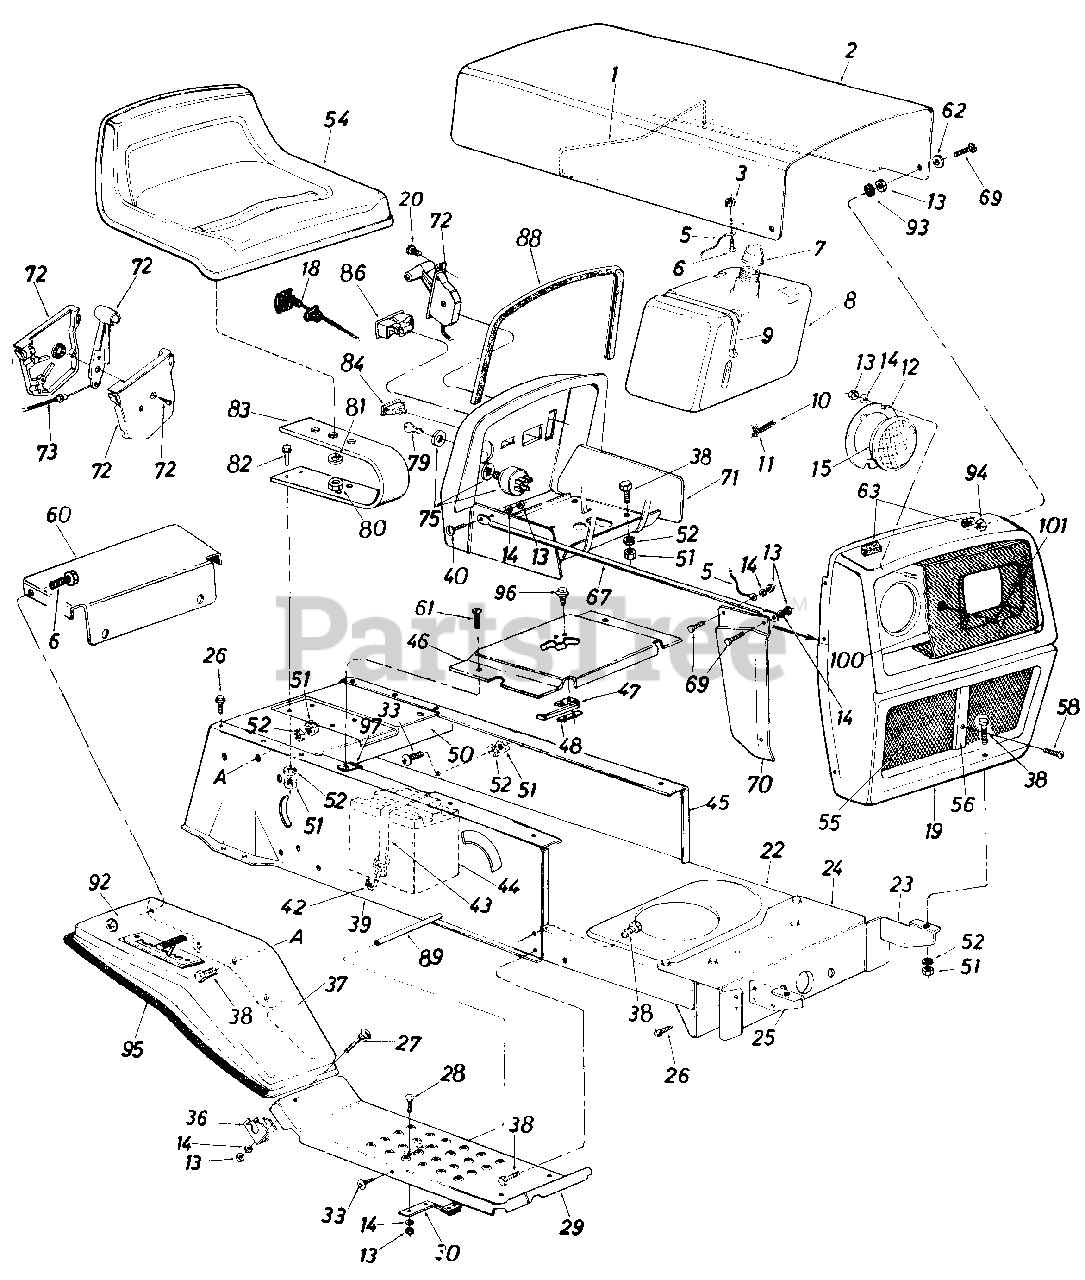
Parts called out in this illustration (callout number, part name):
1	Hood Spring
2	Hood
3	Hex Sems Nut #10-24 Thd.
5	Hood Stop 7" Lg.
6	Truss Hd. Scr. #10-24 x 1/2"
7	Fuel Cap Gauge
8	Fuel Tank
9	Tie Strap
10	Fuel Line
11	Hose Clamp
12	Headlight Retainer
13	Hex Nut 1/4-20 Thd.*
14	L-Wash 1/4" I.D.
15	Headlight
18	Choke Control 29" Lg.
19	Grille Ass'y.
20	Truss Mach. AB-Tap Scr. #10 x .50" Lg.
22	Lower Frame
23	Grille Mount Brkt.-L.H.
24	Front Pivot Brkt.
25	Grille Mount Brkt.-R.H.
26	Hex Wash. Hd. AB-Tap Scr. 5/16 x .75" Lg.
27	Carriage Bolt 1/4-20 x 2.0"*
28	Carriage Bolt 1/4-20 x .62"*
29	Running Board
30	Blade Brake Ass'y.
33	Truss Mach. Scr. 5/16-18 x .75" Lg.*
36	Fender Clamp
37	Fender
39	R.H. Side Frame
40	Hex Bolt 1/4-20 x .62" Lg.
42	Battery Strap Hook
43	Battery Hold Down Strap
44	12-V Battery
45	L.H. Side Frame
46	Shift Cover
47	Reverse Safety Switch
48	Insulator Nut Plate
50	Hitch Plate
51	Hex Nut 5/16-18 Thd.
52	L-Wash. 5/16" I.D.
54	Seat Ass'y.
55	Seat with Safety Switch
56	Moulding
58	Hex Wash. F-Tap Scr. #8 x .38" Lg.
62	Fl-Wash. .281 I.D. x .73 O.D.
63	Foam Strip 3/8 x 1-1/8 x 11/2
67	Grille Support Rod
69	Truss Hd. Scr 1/4-20 x 75"*
70	R.H.-Grille Side Panel
71	Dash Panel Ass'y.
72	Throttle Control Box Ass'y.
73	Throttle Control Wire
75	Ignition Switch
79	Ignition Key
80	Hex Nut 1/2-13 Thd.
81	L-Wash. 1/2" I.D.
82	Hex Bolt 5/16-18 x 1.0'
83	Seat Spring 5.5" High
84	Light Switch
86	Ammeter
88	Molding Strip 27" Lg.
89	Running Board Rod
92	Hex Sems Nut #10-24 Thd.
93	Rubber Wash. 1/2" I.D. x 1.0 O.D. x .25"
94	Hex Sems Ins. L-Nut 1/4-20 Thd.
95	Trim Strip
96	Hex Wash. Hd. AB-Tap Scr. #8 x .50" Lg.
97	Speed Nut #10Z
100	Bezel
101	Truss Scr. #10-24 x .62" Lg.
